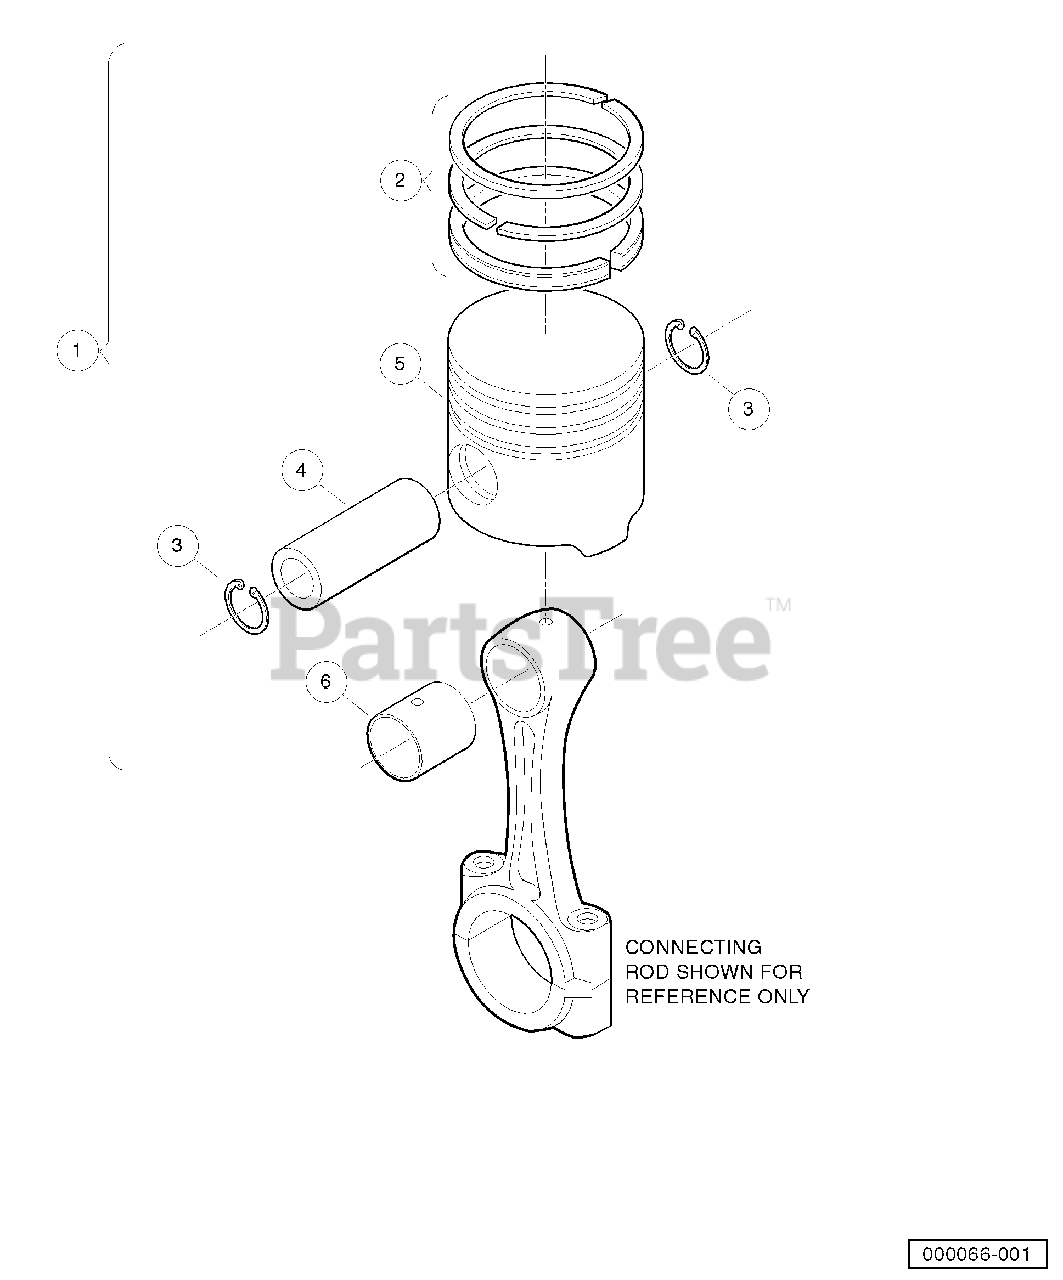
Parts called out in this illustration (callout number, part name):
1	Kit, Piston Rebuild, D722
2	Assy Piston Ring, D722 Std
3	Circlip, Piston Pin
4	Pin, Piston
5	Piston, D722, Std
6	Bushing, Piston Pin, D722
